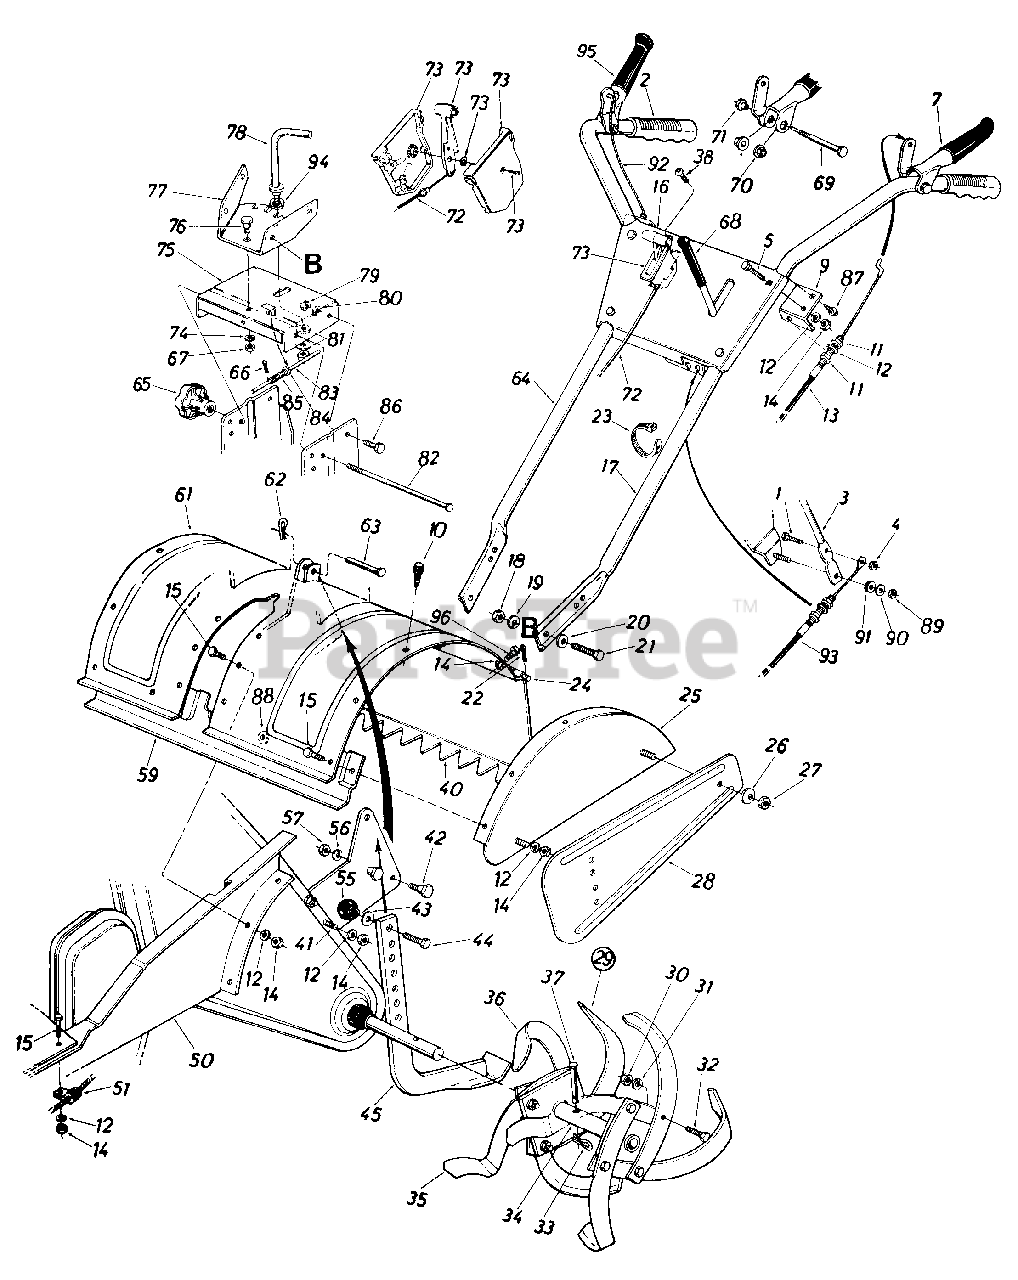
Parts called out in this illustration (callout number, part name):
1	Hex Bolt 1/4-28 x 1.0" Lg.
2	Grip
3	Clutch Lever
4	Hex Cent. L-Nut 1/4-28 Thd.
5	Carr. Bolt 5/16-18 x 1.75"
7	Clutch Grip Ass'y.-L.H.
9	Clutch Cable Bracket
10	Hex Wash. S-Tap Scr. 5/16-18 x .62" Lg.
11	Hex Nut 5/16-24 Thd.
12	L-Wash. 5/16 I.D.
13	Clutch Control Cable
14	Hex Nut 5/16-18 Thd.
15	Hex Bolt 5/16-18 x .75'1 Lg.
19	L-Wash. 3/8" I.D.
20	Bell-Wash. 3/8" I.D.
21	Hex Bolt 3/8-16 x 1' Lg.
22	Cotter Pin 3/32" Dia. x 3/4"
23	Cable Tie
24	Tiller Flap Rod
27	Hex Nut 5/16-18 Thd.
31	L-Wash. 3181' I.D.
32	Hex Bolt 3/8-24 x 1.25" Lg.
33	Hairpin Cotter
38	Truss Mach. AB-Tap Scr. #10 x .5" Lg.
41	Hex Bolt 5/16-18 x 1.0" Lg.
42	Shld. Bolt 1/2" Dia. x .43"
43	Fl-Wash. 3/8" I.D. x 5/8" O.D.
44	Hex Bolt 3/8-16 x 314" Lg.
55	Ball Knob 1-1/4" Dia.
56	L-Wash. 3/8" I.D.
57	Hex Nut 3/8-16 Thd.
63	Clevis Pin 3/8" Dia.
66	Cotter Pin 1/16" Dia. x .75"
67	Hex Cent. L-Nut 3/8-16 Thd.
69	Shoulder Bolt .375" Dia. x 1.37" Lg.
70	Hex Flange Plastic Bearing
71	Shoulder Nut 1/4-20 Thd.
72	Throttle Control Wire
73	Throttle Control Box Ass'y.
74	Bell-Wash. .40" I.D. x 1.13"
79	Hex Cent. L-Nut 3/8-16 Thd.
80	Bell-Wash. .40" I.D. x .88"
81	Bell-Wash. 1/2" I.D. x 1.00"
82	Lock Pin 5/16" Dia. x 8"
83	Lower Sliding Ass'y.
84	Fl-Wash. .291" I.D. x .62"
85	Compression Spring 1" Lg.
86	Shoulder Bolt 1/2" Dia. x .170" Lg.
87	Hex Wash. S-Tap Scr. 1/4-20 x.50" Lg.
88	Bell-Wash. 5/16" I.D.
89	Hex Cent. L-Nut 5/16-18 Thd.
90	Fl-Wash. .344" I.D. x .87"
91	Rubber Wash. .33 I.D. x .87"
92	Control Cable
93	Control Cable
94	Fl-Wash. .62" I.D. x 1.57"
95	Clutch Grip Ass'y.-R.H.
96	Hex Bolt 5/16-18 x 1.25"
14979-0498	Rear Tine Shield - OLD CUB YELLOW (0498)
14979-0638	SHIELD-REAR TINE - MTD/TROY-BILT RED (0638)
14979-0665	SHIELD-REAR TINE - YARDMAN GREEN (0665)
